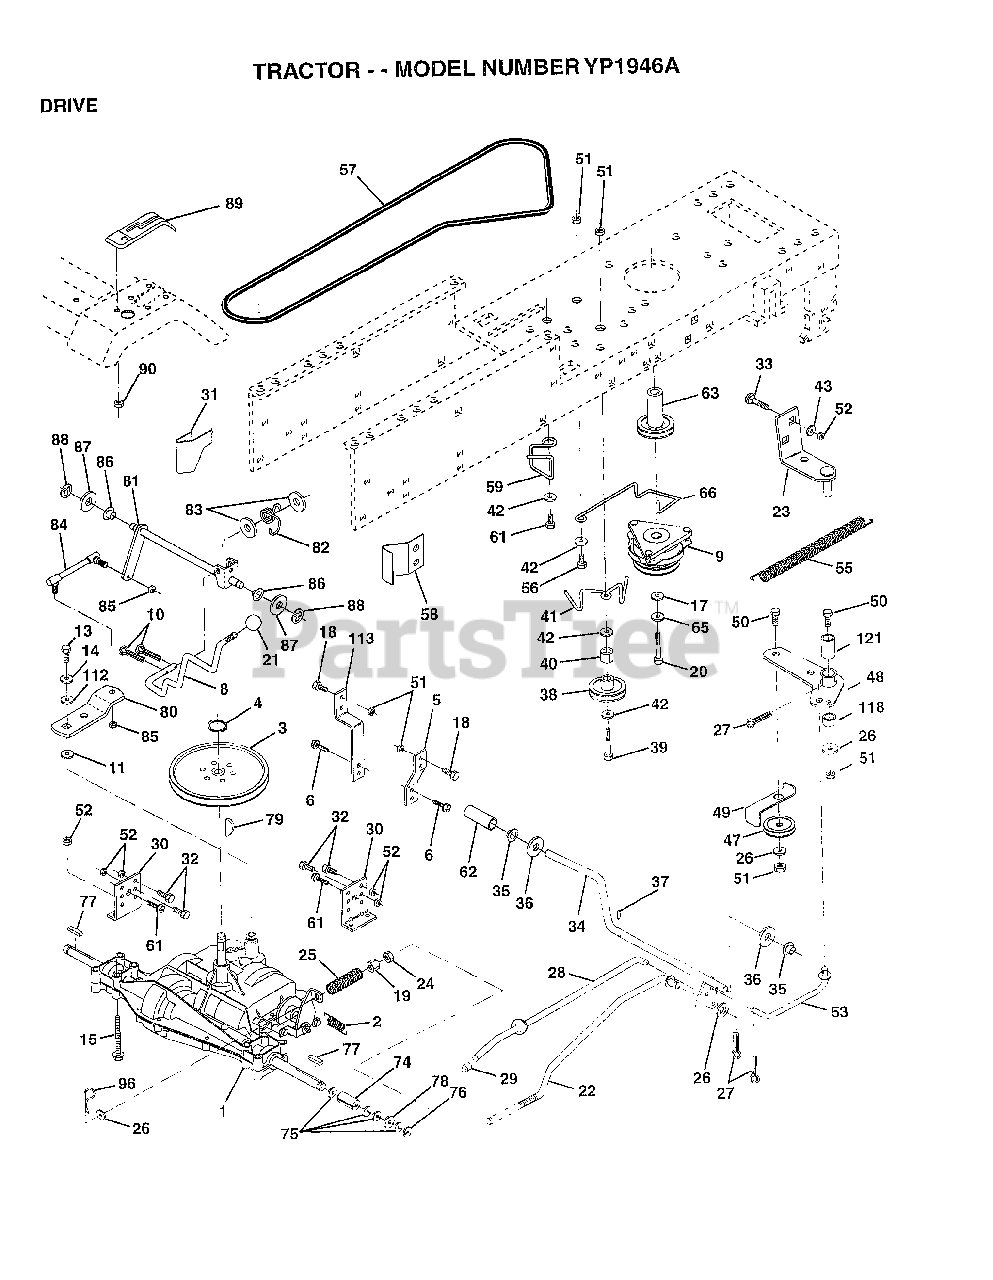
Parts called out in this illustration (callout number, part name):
2	SPRING.BRAKE.RETU
3	PULLEY TRANS
5	STRAP TORQUE
6	SCREW
8	ROD SHIFT FEND YT
10	PIN COTTER 1/8
11	WASH-SHFT PLT LT
13	BOLT.1/4-28.W/PAT
14	LOCKWASHER
15	BOLT.HX.FLG.5/16
17	WASHER
18	BOLT
19	NUT
20	BOLT.7/16-20X4.25
21	KNOB.DUCKHEAD.1/2
22	BRAKE ROD
23	BRACKET.ASM.MTG
24	NUT
25	SPRING ROD LT
26	WASHER
27	COTTER PIN
28	ROD.BRAKE.PARK.LT
29	PLUNGER CAP T
30	TRANSAXLE MTG BKT
31	"KEEPER,BELT LH T"
32	BOLT
33	BOLT
34	SHAFT ASM-PEDAL F
35	NYLON BEARING
36	WASHER LT
38	PULLEY.IDLER.FLAT
39	BOLT
40	SPACER T
42	WASHER
43	WASHER T
48	BELLCRANK ASM
49	RETAIN BELT
53	"LINK, CLUTCH T"
55	"SPRING, RETURN LT"
59	KEEPER BELT CNTSP
61	SCREW
62	"COVER,PEDAL"
63	PULLEY CLU ELEC
65	LOCKWASHER
66	KEEPER-BELT
74	SPACER AXLE
75	WASHER
76	E-RING LT
77	SQUARE KEY
78	WASHER
80	"ARM.SHIFT.20""TIRE"
81	SHAFT.CROS.P930.
82	"SPRING,TORSION"
83	WASHER
84	"ROD.TIE.20""P930LT"
86	BUSHING
87	WASHER D
88	KLIP RING
89	CONSOLE SHIFT
90	NUT
112	WASHER LT
113	"STRAP,TORQUE"
118	SPACER-BELLCRANK
121	NYLINER-CLUTCHING
